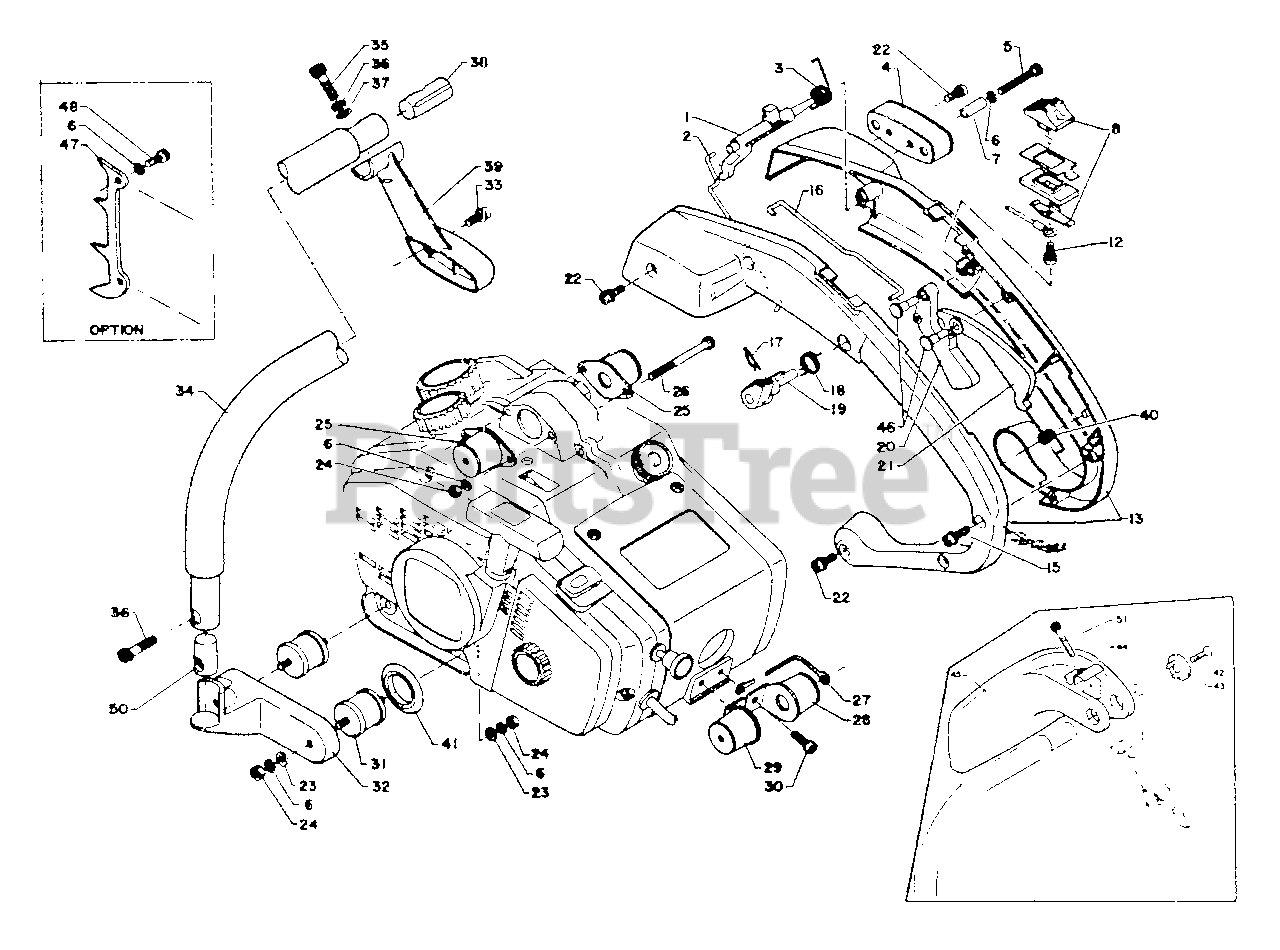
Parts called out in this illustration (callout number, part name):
1	SHAFT, THROTTLE
2	ROD, THROTTLE
3	SPRING, TRIGGER
4	CUSHION RUBBER (L-U)
5	SCREW 4×30
6	WASHER, SPRING 4 MM
7	CUSHION RUBBER SUPPORTER (L-U)
8	IGNITION SWITCH ASSY
13	REAR HANDLE ASSY
15	SCREW 4×14
16	ROD, THROTTLE
17	PIN, LOCKING
18	SPRING, THROTTLE LOCK
19	LOCKOUT, TRIGGER
20	TRIGGER, THROTTLE
21	LOCKOUT, THROTTLE
22	SCREW 4×10
23	WASHER 4 MM
25	CUSHION
26	SCREW - 4×45
27	LEAD - GROUND
28	CUSHION
29	CUSHION
30	SCREW 4×12
31	CUSHION RUBBER (L-L)
32	BRACKET, HANDLE - LOWER
33	SCREW 4×12
34	HANDLE, FRONT
35	BOLT 5×25
36	BOLT 5×20
39	BRACKET, HANDLE - UPPER
40	SPRING, LOCKOUT RETURN
41	STOPPER
42	SCREW - 5×20
43	RETAINER, GUARD
44	STOPPER
45	GUARD
46	PIN
47	BUMPER, SPIKED
48	BOLT 4×10
50	INSERT, FRONT HANDLE
51	BOLT 5×30
